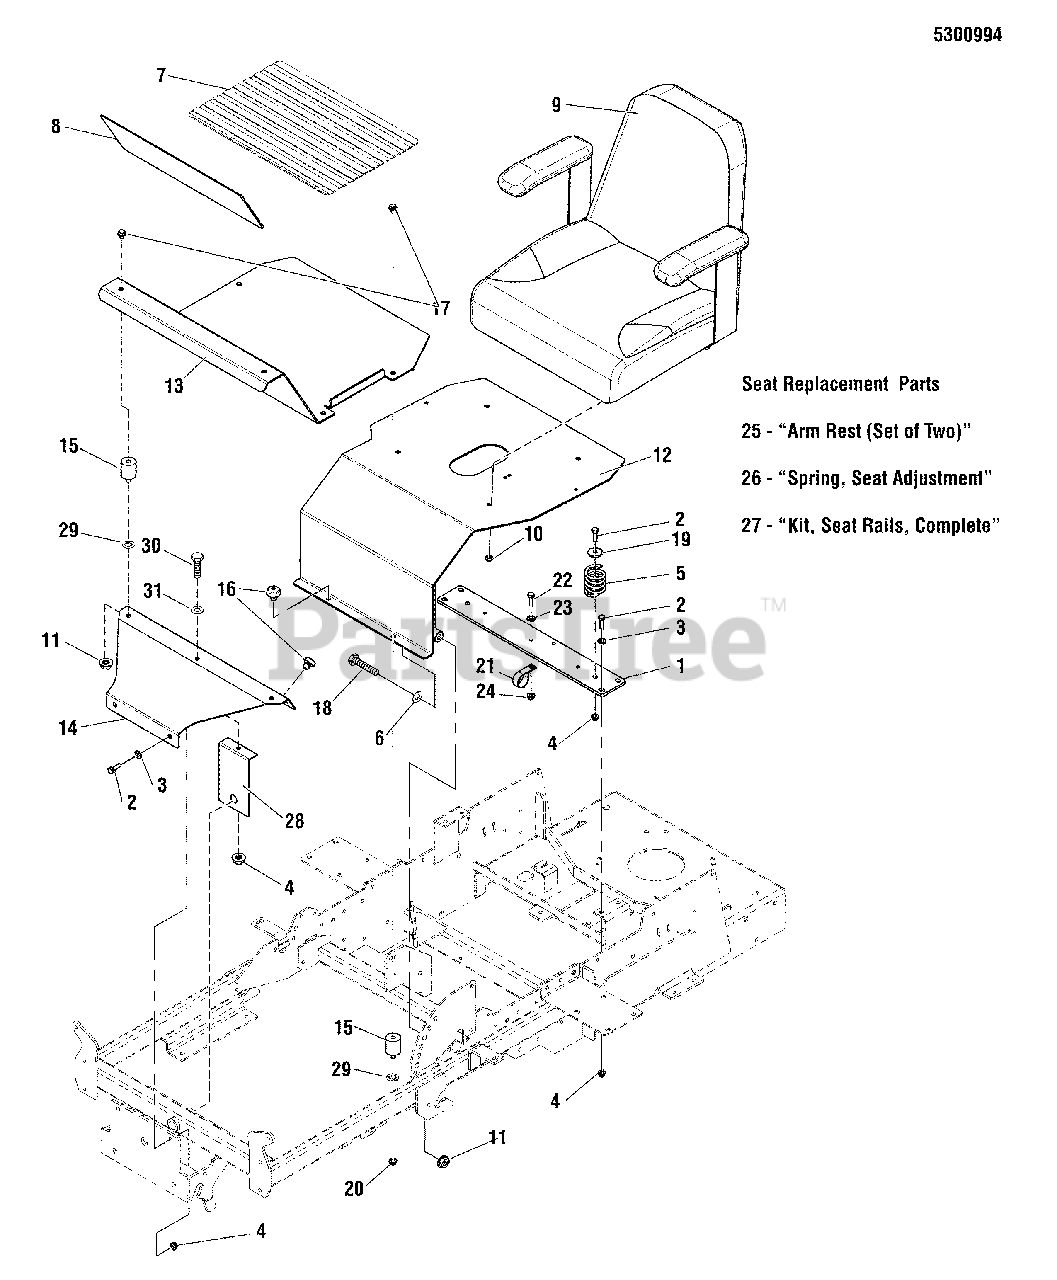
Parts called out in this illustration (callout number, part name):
1	PLATE, SEAT SUPPORT, CONS Z - RED
2	BOLT, 5/16-18 X 1 GD5 YZ
3	WASHER, 5/16 GD.9 FLAT
4	NUT, 5/16-18 HEX NYLOCK FLANGE
5	SPRING, SEAT SUPPORT
6	WASHER, 3/8 SAE
7	SAFETY WALK, FLOOR PLATE, 17.13 X 11.50
8	SAFETY WALK, FLOOR REST, 17.13 X 6.00
9	SEAT, XB-180, NO LOGO, BLACK
10	NUT, 5/16-18 HEX NYLON LOCK
11	NUT, 3/8-16 HEX NYLOCK FLANGE
12	WELD, SEAT PLATE - RED
13	PLATE, FLOOR, SNAPPER ZTR - RED
14	PLATE, FLOOR, FRONT, CONS Z - RED
15	MNT, VBRTN, 30 DURO
16	MNT, VBRTN, RBBR
17	BOLT, 3/8-16 X 5/8, SERRATED UNDER HEAD
18	BOLT, 3/8-16 X 3-1/2" GD5 CZ
19	WASHER, .34 X 1.25 X 10 GA
20	NUT, 3/8-16 HEX SERRATED FLANGE
21	CLAMP, VINYL INSULATED
22	BOLT, 1/4-20 X 3/4 GD5 YZ
23	WASHER, 1/4 SAE
24	NUT, 1/4-20 HEX NYLOCK FLANGE
25	ARM REST, SET OF TWO (SV)
26	SPRING, Extension, Seat Adjustment (BLK or SLVR) (3-1/2" Total unstretched length.)
27	KIT, SEAT RAILS. COMPLETE (SV)
28	PLATE, SUPPORT, FRONT FLOOR - RED
29	WASHER, 3/8" ID, INTERNAL TOOTH
30	BOLT, 5/16-18 X 3/4 GD5
31	WASHER, 5/16" SAE
